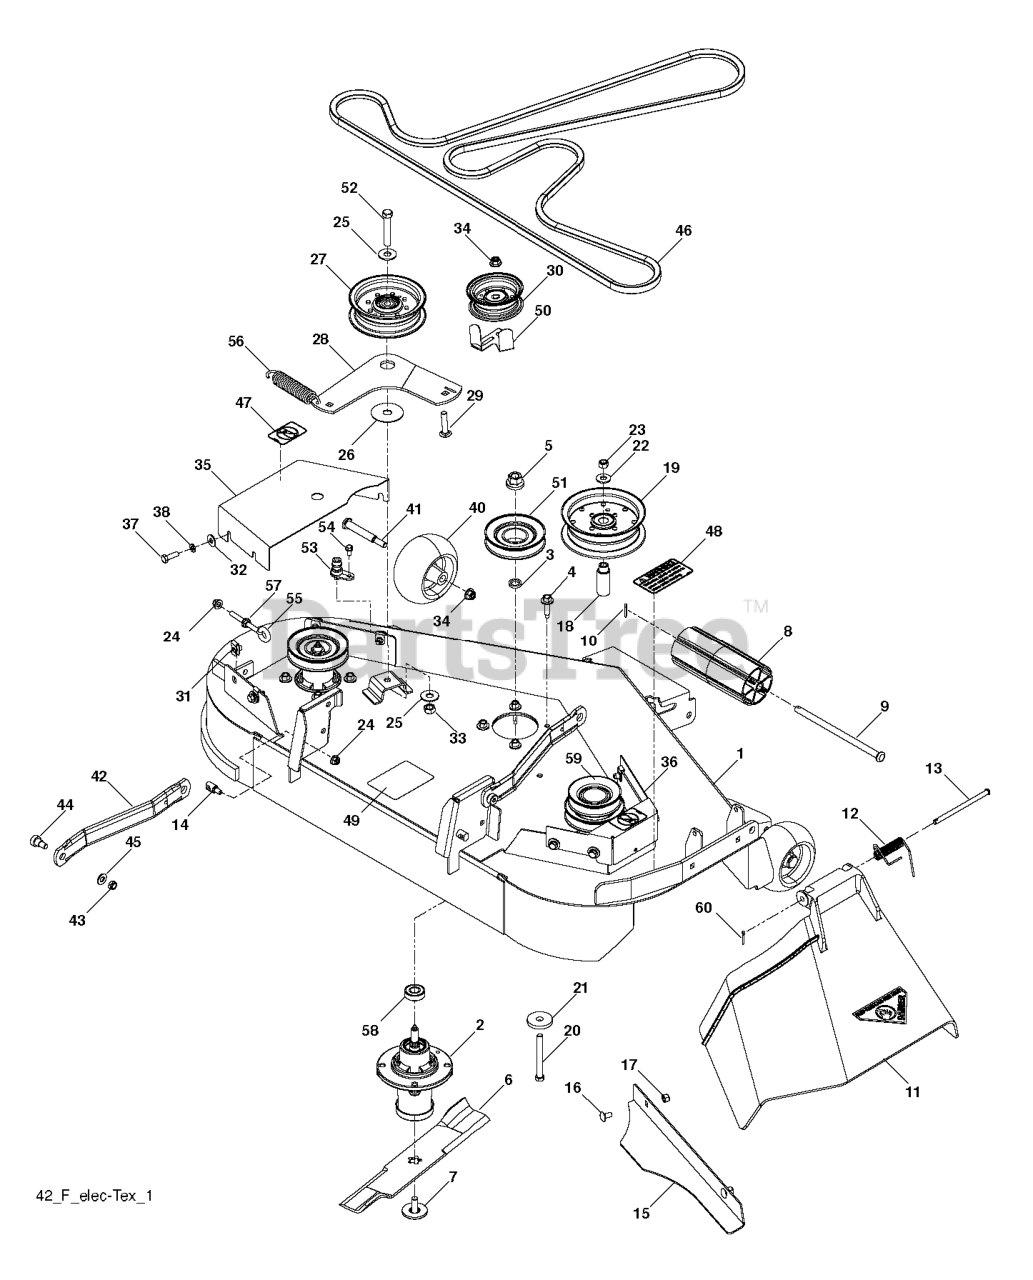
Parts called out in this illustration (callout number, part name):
1	DECK SVC W/DECALS 42 YTH ORNGE
2	MANDREL.DECK.ASSEMBLY
3	WASHER-SPACER
4	WASHER HEAD SCREW
5	LOCKNUT - 9/16
6	BLADE, 14 5/8"
7	BLADE BOLT ASSY-7/16" TB REPL
8	NOSE ROLLER 48"
9	ROD.ROLLER.NOSE.NARROW.48"
11	DISCHARGE CHUTE - 42 PLASTIC
12	SPRING - TORSION
13	PIN, CLEVIS 5/16 X 5.19
14	STUD.FASTNER.W/ANTI-ROTATE
15	CONFINEMENT.PLATE.42".BLACK
16	CARRIAGE BOLT 5/16C X 5/8"
17	NUT 5/16 NYLOC
18	BUSHING, IDLER
19	PULLEY, IDLER
20	HCS 3/8-16 X 3-1/2 GR5 ZD
21	SPINDLE WASHER
22	WASHER 3/8 FLAT
23	NUT 3/8-16 NYLOC
24	5/16-18 NYLOC FLANGE NUT
25	WASHER 7/16 FLAT ZD
27	PULLEY.IDLER.MWR.STATI.LH
28	ARM, IDLER, BLK
29	RHSNB 3/8-16X1-3/4
30	PULLEY.IDLER.FLAT
31	U-CLIP 5/16-18 NUT RETAINER
32	WASHER 5/16 FLAT
33	7/16-14 HEX NUT W/NYL RING ZD
34	NUT 3/8-16 HEX FLG NYLOC ZD
35	SHIELD.BELT.LH.ORANGE
36	SHIELD.BELT.RH.ORG
37	HCS 5/16C X 1
38	WASHER.LOCK.HVY.HLCL.SPR.5/16
40	GAUGE WHEEL
41	SHOULDER BOLT 1/2X2-5/8 ZD SPE
42	ARM.SUSPENSION.MOWER
43	NUT HEX 3/8-16 NYLON, THIN
44	SB 3/8-16 X 3/8 SKT HD ZD
45	WASHER 3/8 SAE FLAT
46	BELT, 42" FAB DECK
47	DECAL, NO STEP
48	DECAL, CAUTION
49	DECAL.MOWER.SCH.48/54
50	BELT GAURD
51	PULLEY, MANDREL 4.08 OP
52	BOLT 7/16-14 X 2-1/2 GR 5 ZD
53	PORT.WASHOUT
54	BOLT 1/4-20 X 1/2 HWST
55	EYE BOLT 5/16 X 3.50
57	NUT 5/16C WHIZ
58	BEARING, BALL
59	PULLEY, COLLECTION 42
60	RETAINER CLIP
